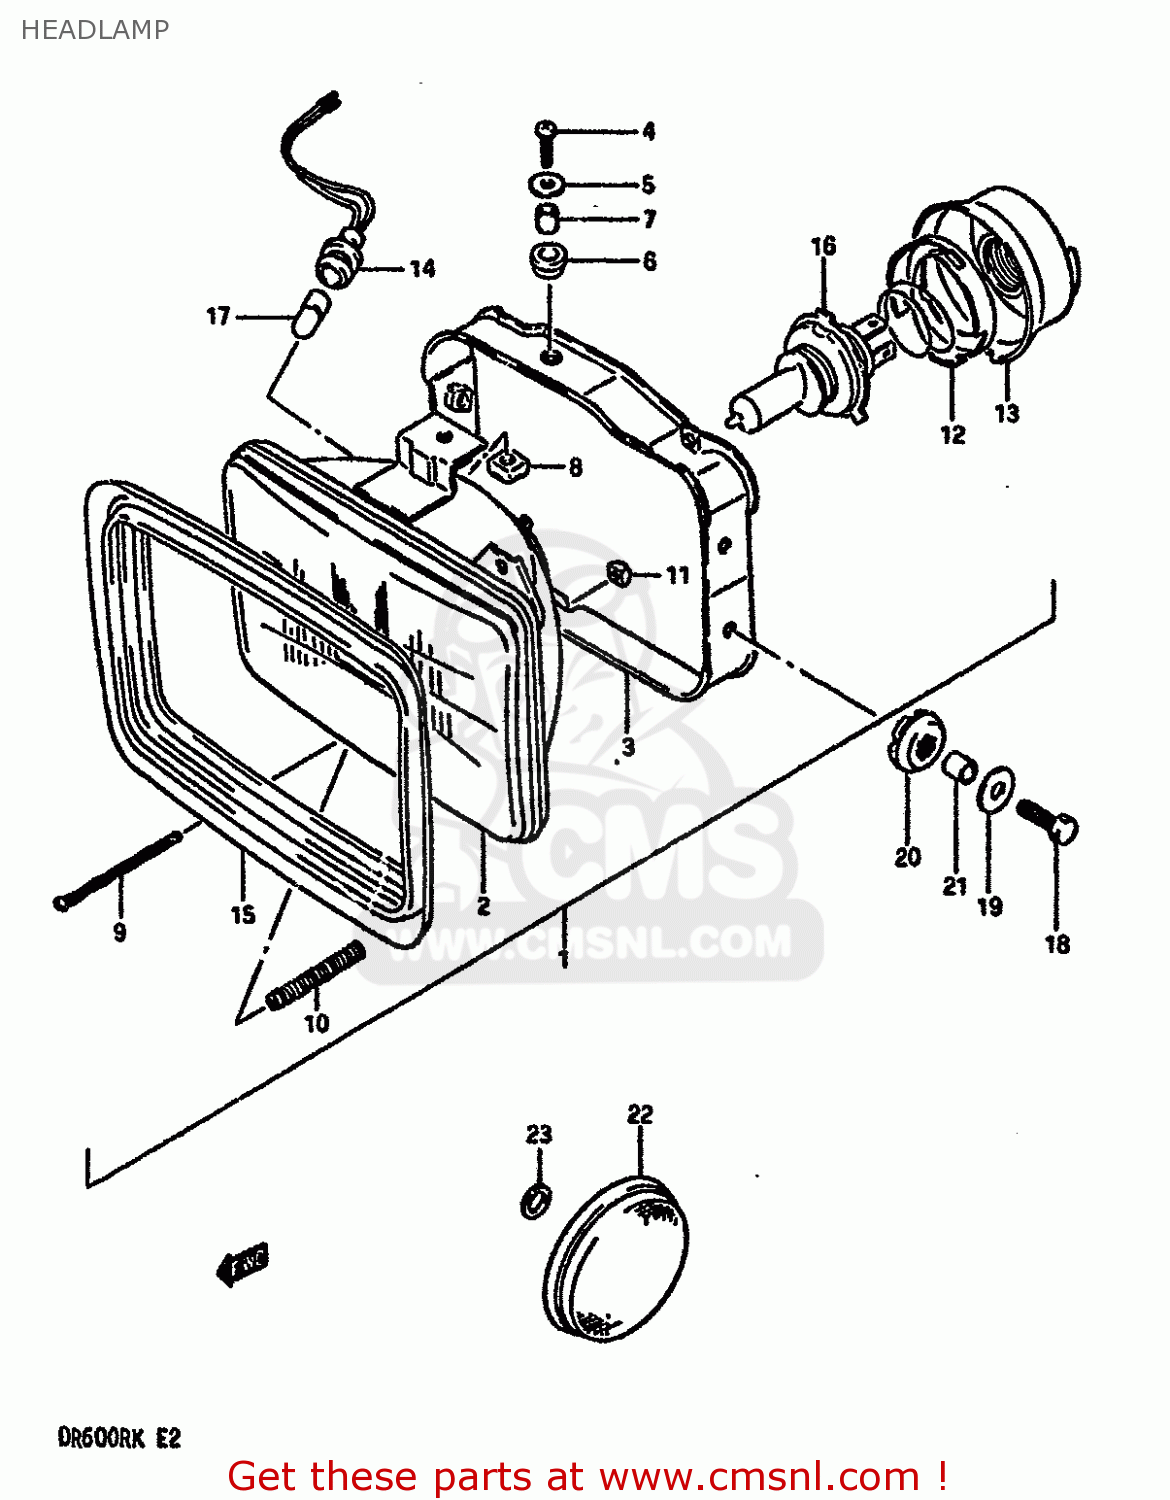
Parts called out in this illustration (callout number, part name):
1	HEADLAMP ASSY
2	UNIT
3	HOUSING
4	SCREW 5X20
5	WASHER
6	CUSHION
7	SPACER
8	NUT
9	SCREW,HEADLAMP ADJUST
10	SPRING
11	NUT
12	HOLDER,BULB
13	COVER,SOCKET
14	SOCKET,PARKING
15	SHADE
16	BULB(12V60/55W,H4)
17	BULB(12V4W)
18	BOLT
19	WASHER (6.5X20X1.2)
20	CUSHION
21	SPACER (6.8X10X10)
22	REFLECTOR,REFLEX FR
23	LOCK WASHER
